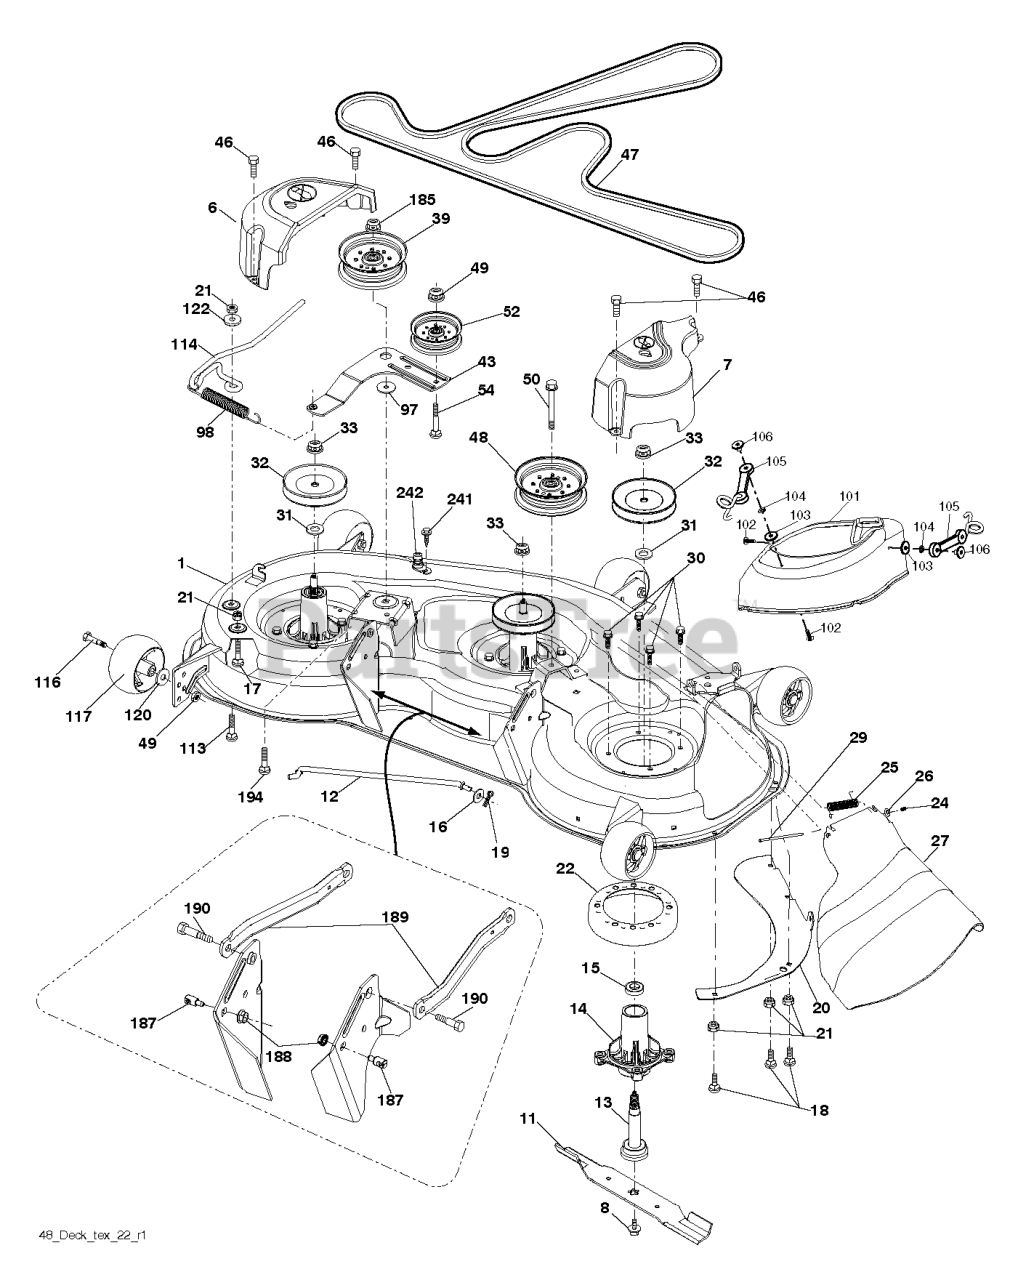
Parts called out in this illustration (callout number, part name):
1	DECK.WLDMT.W/TUBES.48".OR.RP
6	COVER.MANDREL.LH.48"(2 2)
7	COVER.MANDREL.RH.48"
8	BOLT.WASHER.ASM.7/16-2
11	48" HI-LIFT BLADE
12	ROD.ANTI.SWAY.48/54"K4
13	SHAFT ASM MANDREL
14	RP.HOUSING.MANDREL.4PT.
16	WASHER
17	BOLT.CARR.5/16-18X5/8.SHORT
18	BOLT
19	PIN.COTTER.5/16.BOW TI
20	BAFFLE, VORTEX MWR
21	LOCKNUT
22	STRIPPER.MANDREL.ROUND.BLACK
24	CAP-SLEEVE LT
25	SPRING, TORSION
26	NUT PUSH M
27	DEFLECTOR SUBS TO 532 180655
29	ROD.HINGE
30	SCREW, WASHER HEAD
31	WASHER.SPACER.MANDREL
32	PULLEY MANDREL
33	NUT.FLANGE.LOCK.TOP
39	RB PULLEY.IDLER.4.50/HUB SPEC
43	ARM.IDLER
46	SCREW.1/4-20X5/8
47	BELT.DRIVE.DECK
48	PULLEY.IDLER.2006
49	NUT LOCK FLG 3/8-16 UNC
50	SCREW TT 3/8-16X2-1/4 UNC
52	PULLEY.IDLER.48"PRIMARY
54	BOLT.3/8-16X1.50
98	SPRING, DECK DRIVE
101	COVER.MULCH.48"
102	SCREW
104	LOCKWASHER #10
105	LATCH ASSY
106	WELDNUT
113	BOLT CRT
114	ROD.TENSION.RELIEF.TEX (2 2)
116	BOLT.SHOULDER.3/8-16X3-5/8.
117	RP WHEEL. GUAGE RALLY
120	WASHER
122	BUSHING.RELIEF.TENSION
185	NUT.LOCK.FLANGE.7/16
187	STUD.FASTNER.W/ANTI-ROTATE
188	NUT LOCK HEX FLANGE 5/16-18
189	ARM.SUSPENSION.MOWER
190	BOLT.SHOULDER
194	BOLT.HEX.WASHER.HEAD.7/16-24X
241	SCREW.TT.#10-32X.5.3/8.FLANGE
242	PORT.WASHOUT
